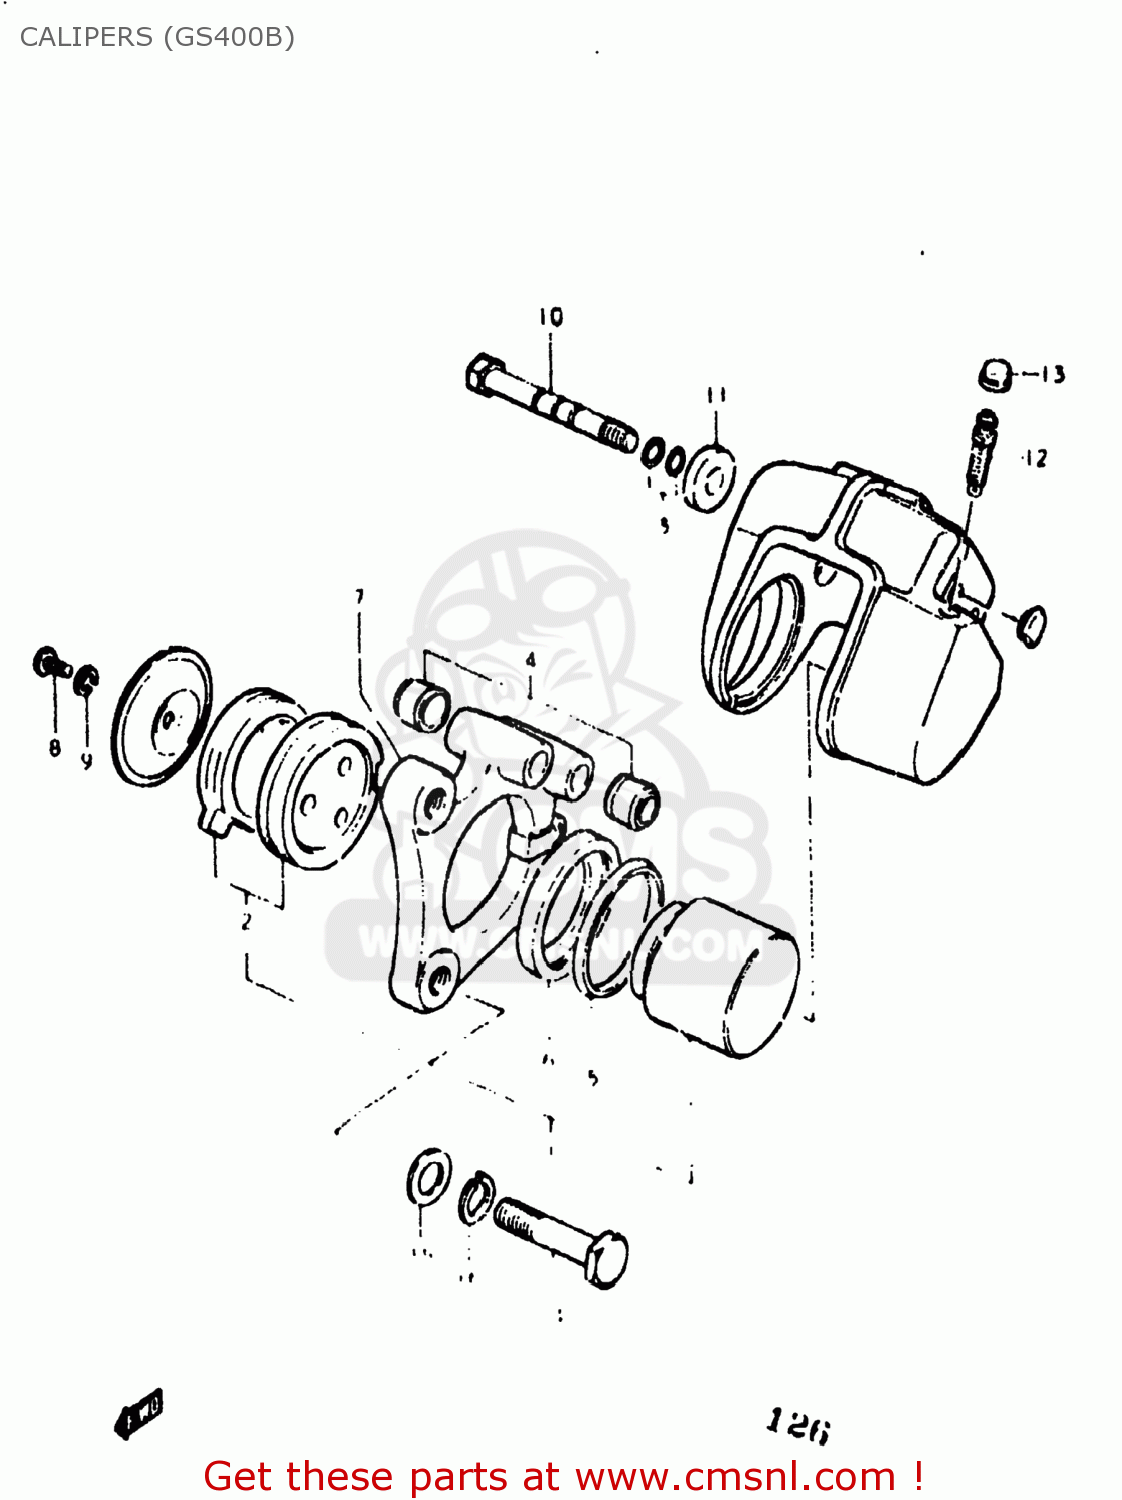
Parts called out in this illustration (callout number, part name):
1	PISTON SET
2	59302-45830 (MCA)
3	O RING,CALIPER AXLE
4	COVER,AXLE DUST
5	SEAL,FR CALIPE
6	BOOT,PISTON
7	HOLDER CALIPERS
8	SCREW 6X12
9	LOCK WASHER
10	AXLE,CALIPER
11	WASHER,AXLE
12	BLEEDER
13	CAP,BREATHER
14	BOLT
15	WASHER
16	LOCK WASHER
